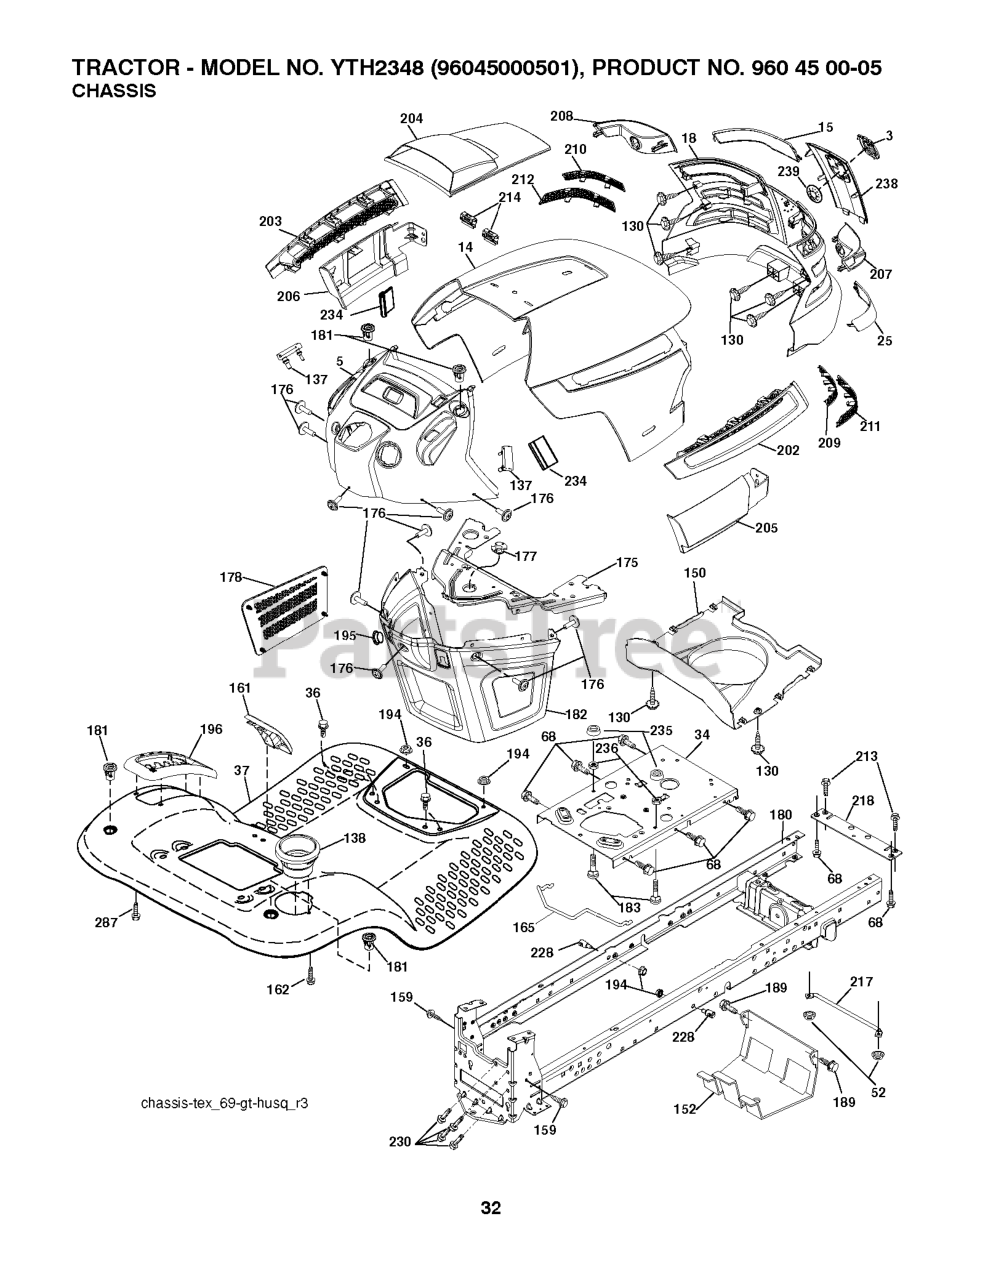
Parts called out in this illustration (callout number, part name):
3	RP LOGO
5	DASH.ASM.HUSQ.GT.E.RECT.W/CK
7	BOLT.SHOULDER
14	HOOD
15	LENS.LH.TEX.GT.HUSQ.CL
18	GRILL.ASM.HUSQ.TG/CRD.W/TRIM
25	LENS.RH.TEX.GT.HUSQ.CL
34	PLATE.ENGINE.WELDED.CHASSIS
36	SCREW 5/16"
37	FENDER.TLT.W/CPH.W/FW.ORANGE
52	LOCKNUT
68	Screw 5/16-18 x 1/2 Hex, Self Tapping 5/16-18 x 1/2
130	SCREW.#10 X 0.750.BOS
137	BUMPER DASH
138	CUPHOLDER.TL.TEX.418
150	AIR.DUCT.HOOD.TEX.GT.HUSQ
152	SHIELD.BROWNING.W/TEX
161	WINDOW FUEL
162	SCREW.HI-LO.CONSOLE
165	SUPPORT.TANK.REAR.W/TEX
175	PLATE.CROSSMEMBER.HUSQ
176	SCREW.#10-24X5/8.RN.QU
177	BUSHING, STEERING
178	CARGO.ASM.NET.TXGT.W/C
180	CHASSIS
181	BUSHING.MNT.FEND.CRGO.
182	DASH.LOWER.COMMON.12V.ADAPTOR
183	BOLT.5/16-18X1-1/4 FULL.THREAD
189	SCREW
194	NUT LOCK HEX FLANGE 5/16-18
195	PLUG.HOLE.DASH.LOWER.12V.BLK
196	RP CONSOLE.ASM.DECKLFT.GR/RBT.
202	VENT.SIDE.HOOD.HUSQ.RH.GREY
203	VENT.SIDE.HOOD.HUSQ.LH.GRAY
204	HOOD VENT
205	SKIRT.HOOD.SIDE.HUSQ.RH.GREY
206	SKIRT.HOOD.SIDE.HUSQ.LH.GREY
207	BEZEL.RH.TEX.GT.HUSQ
208	BEZEL.LH.TEX.GT.HUSQ
209	INSERT.HEX.GRILL.HUSQ.GREY
210	INSERT.HEX.GRILL.HUSQ.
211	INSERT.HEX.GRILL.HUSQ.
212	INSERT.HEX.GRILL.HUSQ.
213	BOLT
214	CLIP.RETAINER.TINNER.
217	ROD.PIVOT.HOOD
218	X-PIECE.HOOD.STOP.NON/
222	SCREW.1/4-20X5/8
228	STUD.FASTNER.W/ANTI-ROTATE
234	BUMPER.HOOD.TEX.HUSQVARNA
235	SPACER FENDER
236	NUT.CENTERLOCK.5/16-
238	TRIM.HUSQ.TG/CRD.SERVICE
239	NUT PUSH M
287	SCREW 1/4X20
